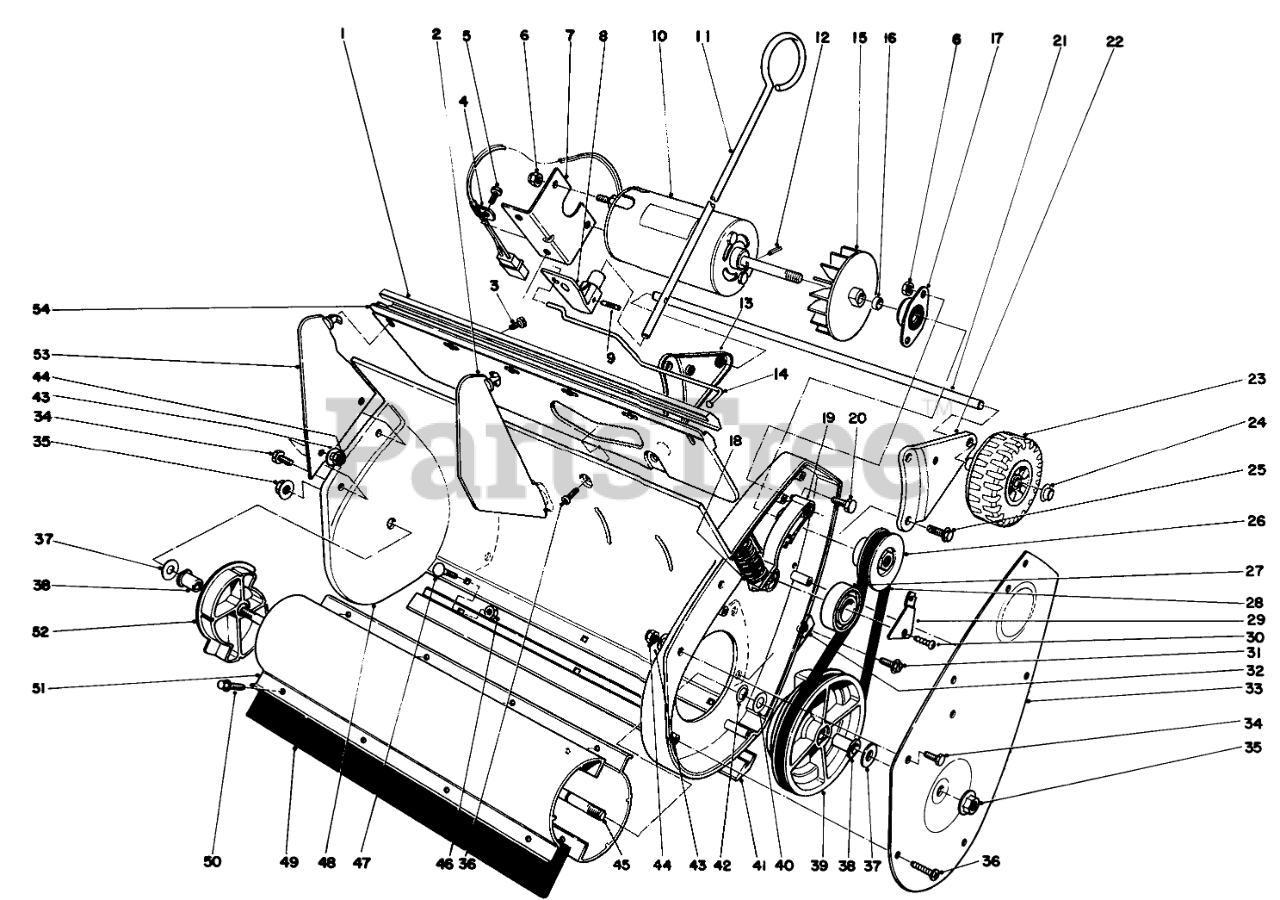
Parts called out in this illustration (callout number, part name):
1	MOULDING
2	INNER VANE
3	10-16 X 3/8 THDG SCREW
4	CLIP-CLOSED, INSULATED
6	NUT-LOCK, NI
7	MOUNTING BRKT B
8	VANE ADJ BRKT
9	GROOVE PIN
10	Motor
11	VANE ADJ ROD
12	SPRING PIN
13	Bracket R.H.
14	Linkage Vane Adjustment
16	SPACER
17	FLANGED BEARING ASM.
18	IDLER COMP. SPRING
19	IDLER ARM
20	SCREW-HH
21	AXLE SHAFT
22	Wheel Bracket L.H.
23	S-120 WHEEL
24	PUSHNUT-CAP, WASHER
25	Screw
26	DRIVE PULLEY
27	BEARING-BALL
29	IDLER PULLEY RETAINER
31	SCREW-HWHTF
32	NUT-TYPE J
33	BELT CASE COVER
34	SCREW-HWH
35	NUT-HF
36	Screw
37	THRUST WASHER (THICK)
38	BUSHING ROTOR
39	Pulley-Driven
40	WASHER-THRUST
41	SCRAPER-SERVICE
42	RING-RETAINING
43	Washer
44	NUT-LOCK, NI
45	ROTOR SHAFT
46	NUT-KEPS
47	SCREW-CARR
48	HOUSING, S-120 HID
49	Blade-Rotor
50	TSCREW-HWH
51	ROTOR
52	END CAP ROTOR
53	OUTER VANE
54	Vane Mount
